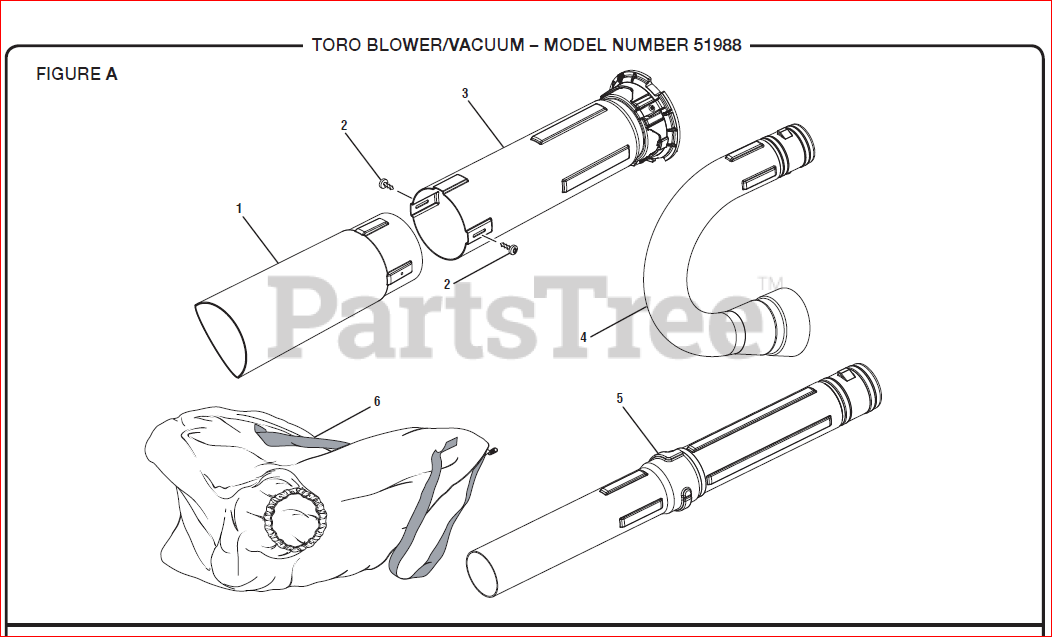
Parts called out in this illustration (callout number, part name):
1	Lower Vacuum Tube
2	Vacuum Tube Screw (10-14 x 1/2 in., T25 Torx Truss Hd. T.F.)
3	Upper Vacuum Tube
4	Vacuum Bag Adaptor
5	Upper and Lower Blower Tube Assembly
6	Vacuum Bag w/Shoulder Strap
